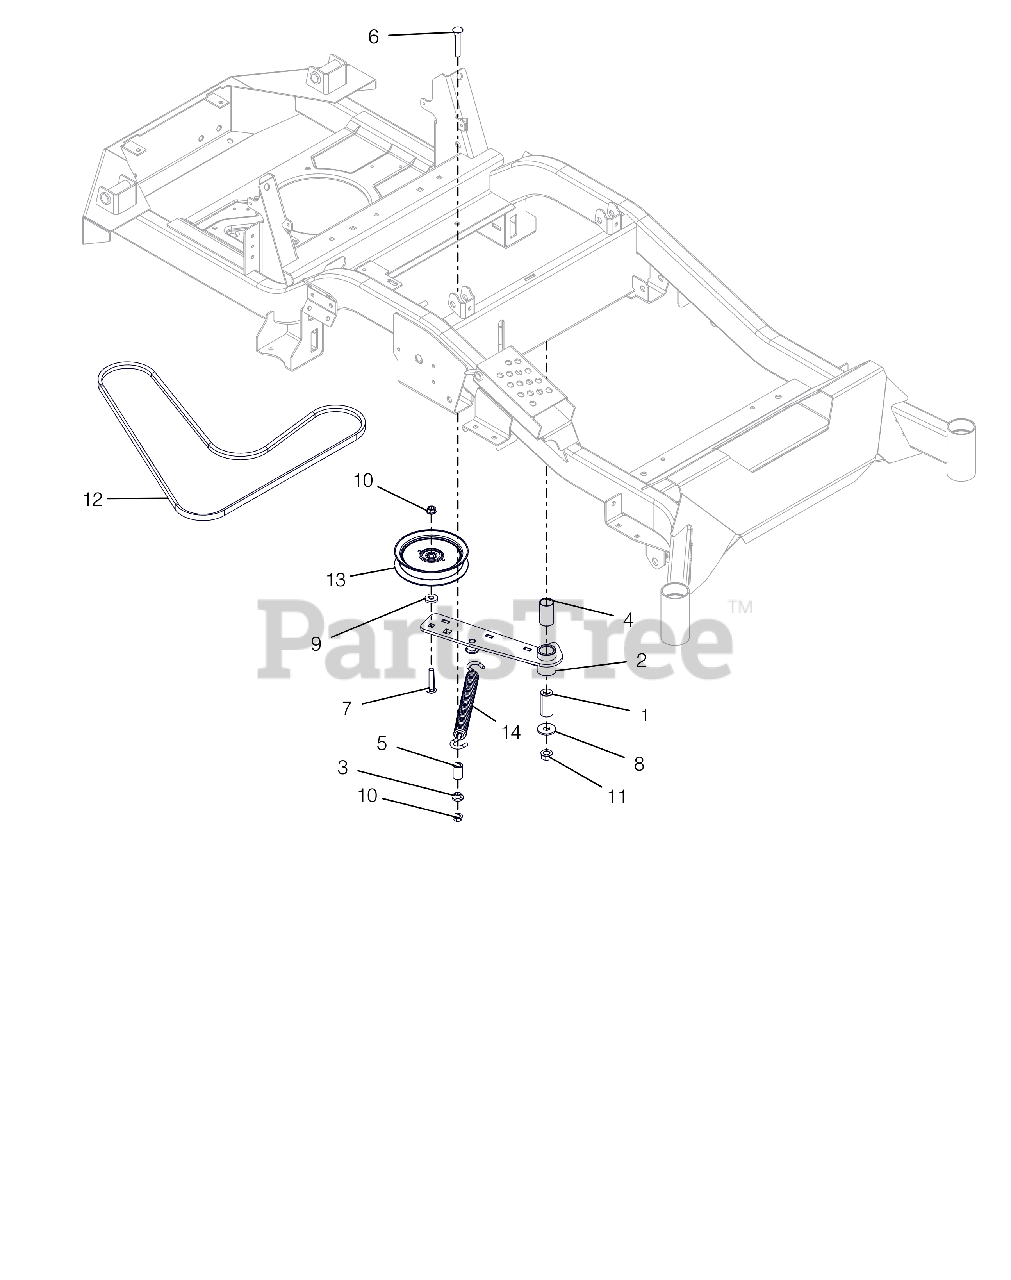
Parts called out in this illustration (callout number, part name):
1	BSHG, SPCR .502X.997X2.03 PM
2	WLDMT, HYDRO DRIVE IDLER ARM
3	BSHG-FLG .385X.500X.875X.406
4	BSHG, 1.00X1.125X1.937
5	BUSHING, SLV .380X.750X1.190
6	BLT-RDHDSQSHK, 38-16X2.50 G5YZ
7	@BLT-RDHDSQNK .38-16X2.00 G5YZ
8	WSHR-FL-STL.511X1.441X.125 YWZ
9	WSHR-FL-STL .406X1.00X.188 YWZ
10	@NUT-LK-TOP-FLG .38-16 YWZC
11	@NUT-LK-TOP-FLG .50-13 YWZC
12	V-BELT, 4L-WRAPPED
13	IDLER, FLAT 5.00"
14	SPRING, EXTENSION
